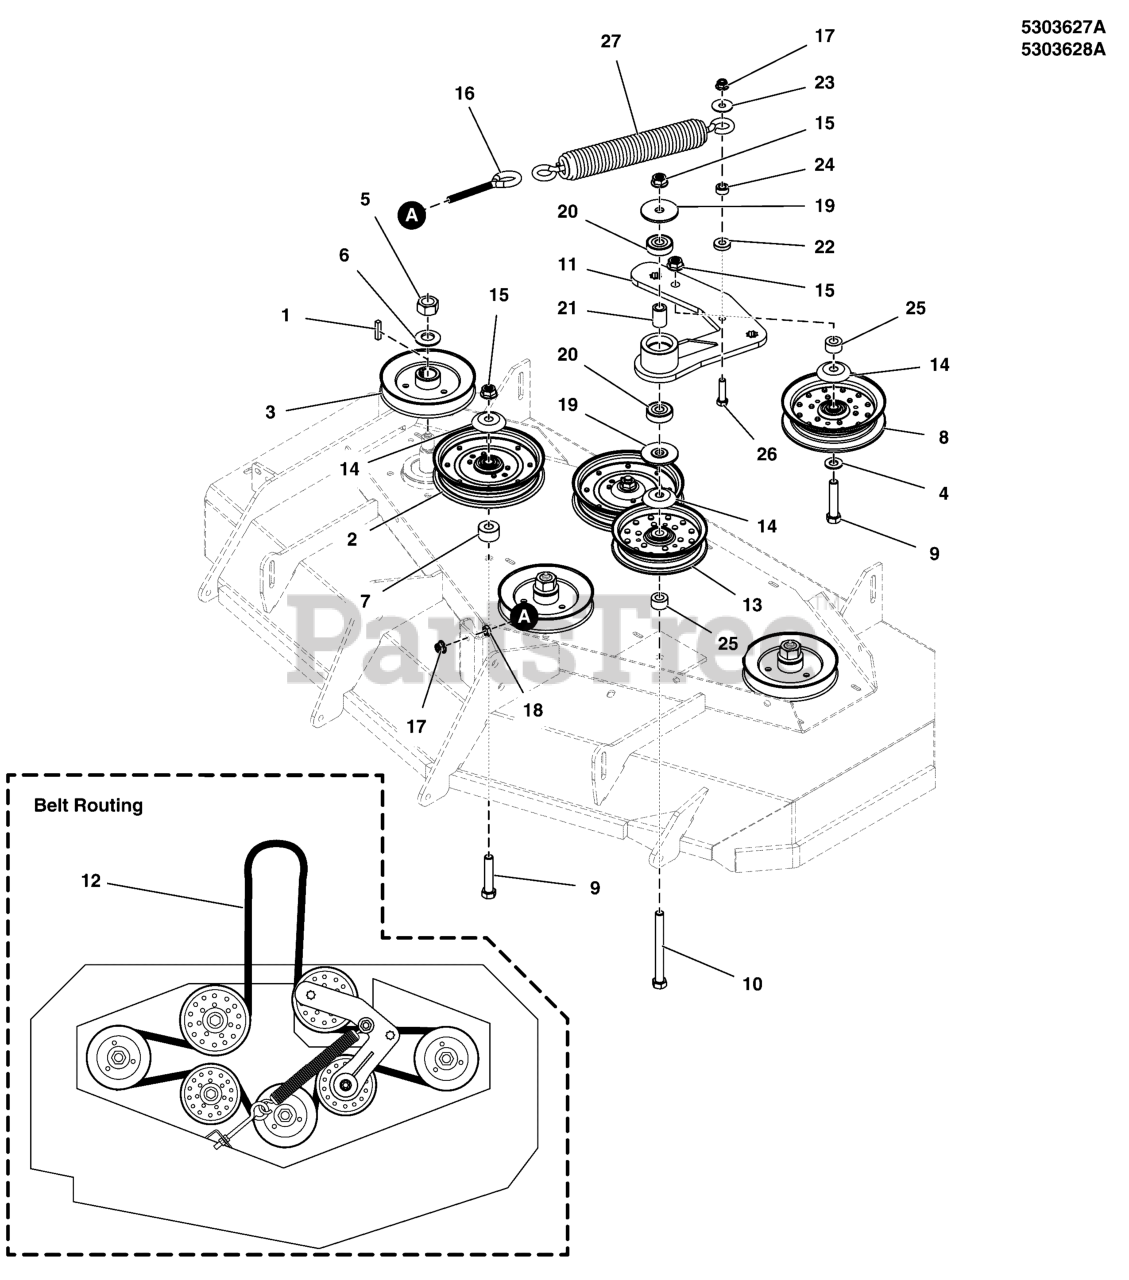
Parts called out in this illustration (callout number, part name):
1	KEY, 1/4" SQ. X 1-1/4
3	PULLEY, 5.540OB X .985ID, SINGLE B-SEC
4	WASHER, 1/2 SAE
5	NUT, 3/4-16 Hex
6	WASHER, 3/4 BELLEVILLE CL/ZC
7	SPACER, .52 X 1.25 X .70, PM, CZ
9	BOLT, 1/2-13 X 2-1/2" GD5 CZ
10	BOLT, 1/2-13 X 5" GD5 YZ
11	WELD, IDLER ARM - BLK
12	BELT, 5V, 147.40"EL, LRG ARAMID,WRPD, RC
13	PULLEY, IDLER, 5" OD, 1" FACE, 5.75 FLANGE
14	SHIELD, PULLEY BEARING, CZ
15	NUT, Hex Flange, Nylock, 1/2-13
16	EYE BOLT, 3/8-16 X 5, 2.88THRD, 1EYE, CZ
17	NUT, 3/8 - 16 HEX NYLOCK FLANGE
18	NUT, 3/8-16 HEX JAM
19	SPACER, IDLER ARM, 1/2 X 2.25
20	BEARING, 6203-1/2", SEALED
21	SPACER, .51 X .84 X 1.22, PM, CZ
22	SPACER, .39 X 1.00 X .25, PM, CZ
23	WASHER, 3/8" Fender
24	SPACER, .39 X .75 X .38, PM, CZ
25	SPACER, .52 X 1.00 X .56, PM, CZ
26	BOLT, 3/8-16 X 1-1/2" GD5 CZ
27	SPRING, EXT, 1.5ODX12.25X.234WIRE BLK
